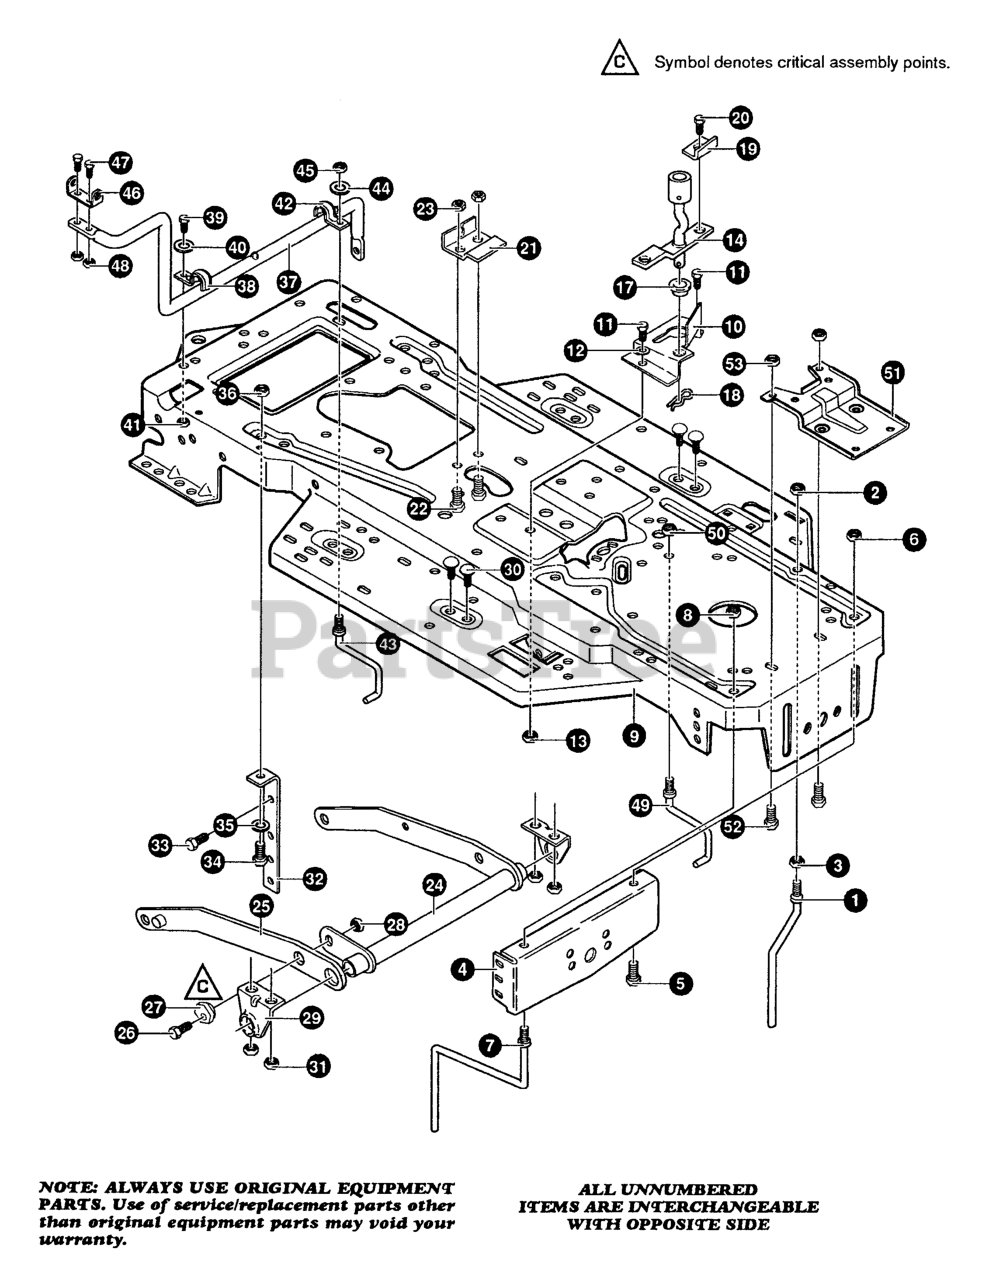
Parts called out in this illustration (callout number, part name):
1	GUIDE, BELT
2	NUT, 5/16-18
3	NUT, 3/8-16
4	BRACKET, FRONT AXLE
5	SCREW, 5/16-18 x 0.75
6	NUT, 5/16-18
7	GUIDE, BELT
8	NUT, 5/16-18
9	FRAME, MAIN
10	BRKT, CLUTCH ENGAGE LEVER
11	SCREW, 5/16-18 x 1.00
12	WASHER, FLAT .344 x .69 x .065
13	NUT, 5/16-18
14	ASSEMBLY, CLUTCH LEVER LOWER
17	BEARING, FLANGE
18	PIN, HAIR
19	BRACKET, SWITCH ENGAGE
20	SCREW, 5/16-18 x 0.75
21	BRACKET, FRAME CABLE
22	SCREW, 1/4-20 x .75
23	NUT, 1/4-20
24	LIFT ASSEMBLY, LH
25	LIFT ASSEMBLY, RH
26	SCREW, 5/16-18 x 1.00
27	NUT, ADJUST
28	NUT, 5/16-18
29	BRACKET, REAR HANG
30	BOLT, 5/16-18 x .63
31	NUT, 5/16-18
32	BRACKET, STABILIZER
33	SCREW, 3/8-16 x 1.25
34	SCREW, 5/16-18 x 1.00
35	WASHER, FLAT .344 X .69 x .065
36	NUT, 5/16-18
37	LEVER, SHIFT-LOWER
38	CLIP-SHIFT LEVER
39	SCREW, 5/16-18 x 0.75
40	WASHER, FLAT .391 x 1.00 x .125
41	NUT, 5/16-18
42	CLIP-SHIFT LEVER
43	GUIDE, BELT
44	WASHER, FLAT .391 x 1.00 x .125
45	NUT, 5/16-18
46	BRACKET, PIVOT SHIFT LEVER
47	SCREW, 1/4-20 x .75
48	NUT, 1/4-20
49	GUIDE, BELT, RH
50	NUT, 5/16-18
51	BRACKET, MUFFLER
52	SCREW, 5/16-18 x 0.75
53	NUT, 5/16-18
